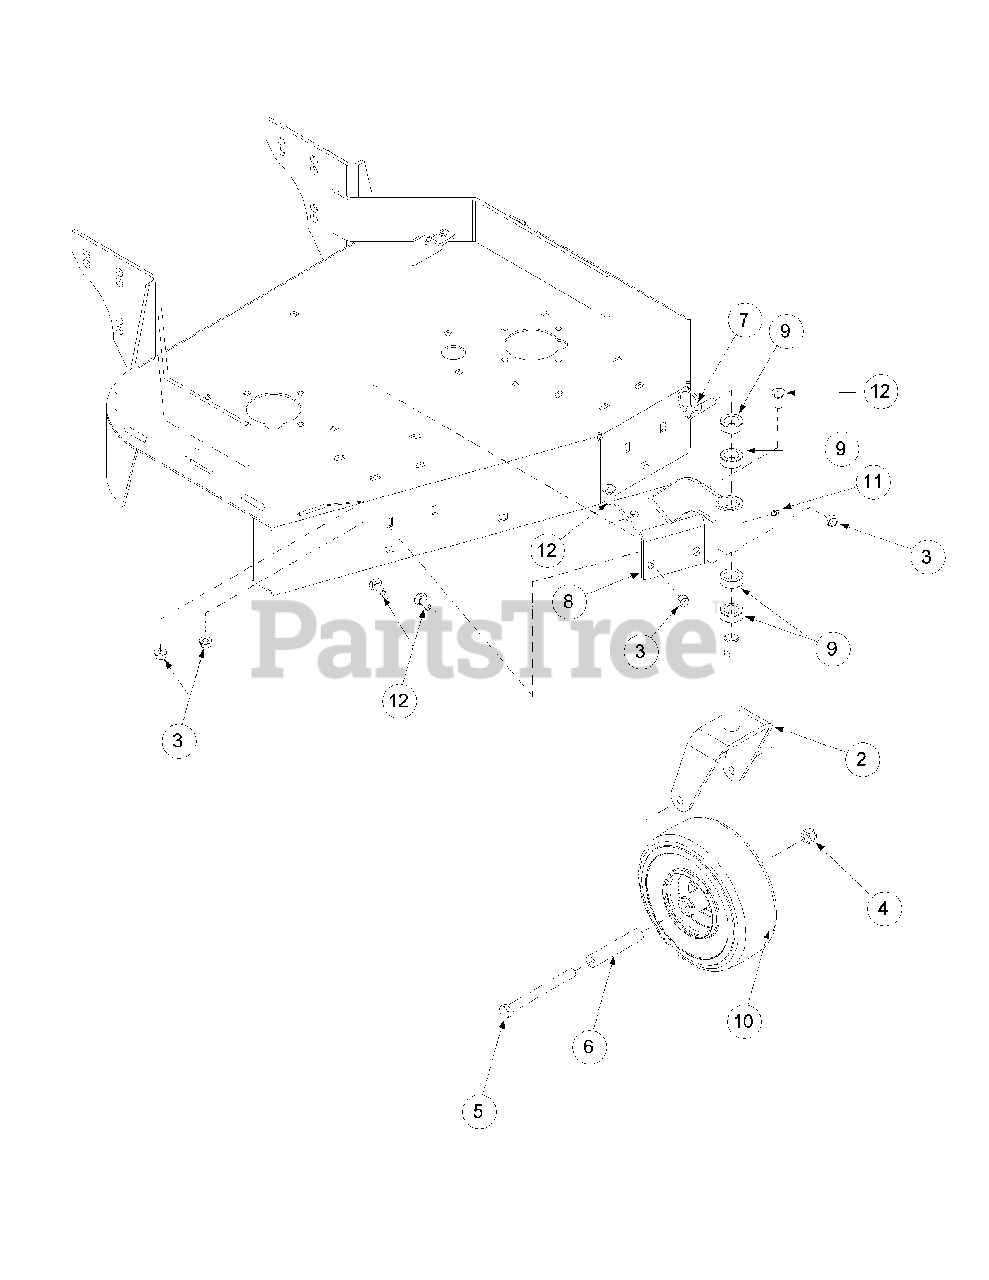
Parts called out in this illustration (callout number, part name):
1	Lubricant Grease by Ounce
2	Caster Yoke Assembly, Weldment
3	Nut, Hex Flange Lock, 3/8-16
4	Lock Nut, Nylon Insert, 1/2-13
5	Hex Cap Screw, 1/2-13, 5.50
6	Spacer Wheel
7	Klik Pin, 1.75
8	Caster Bracket Weldment
8	Caster Bushing
9	Spacer, Caster
10	Wheel Assembly, 9.0 x 3.50-4
11	Grease Fitting, 1/4-28 x 3/16
12	Carriage Bolt, 3/8-16 x 1
